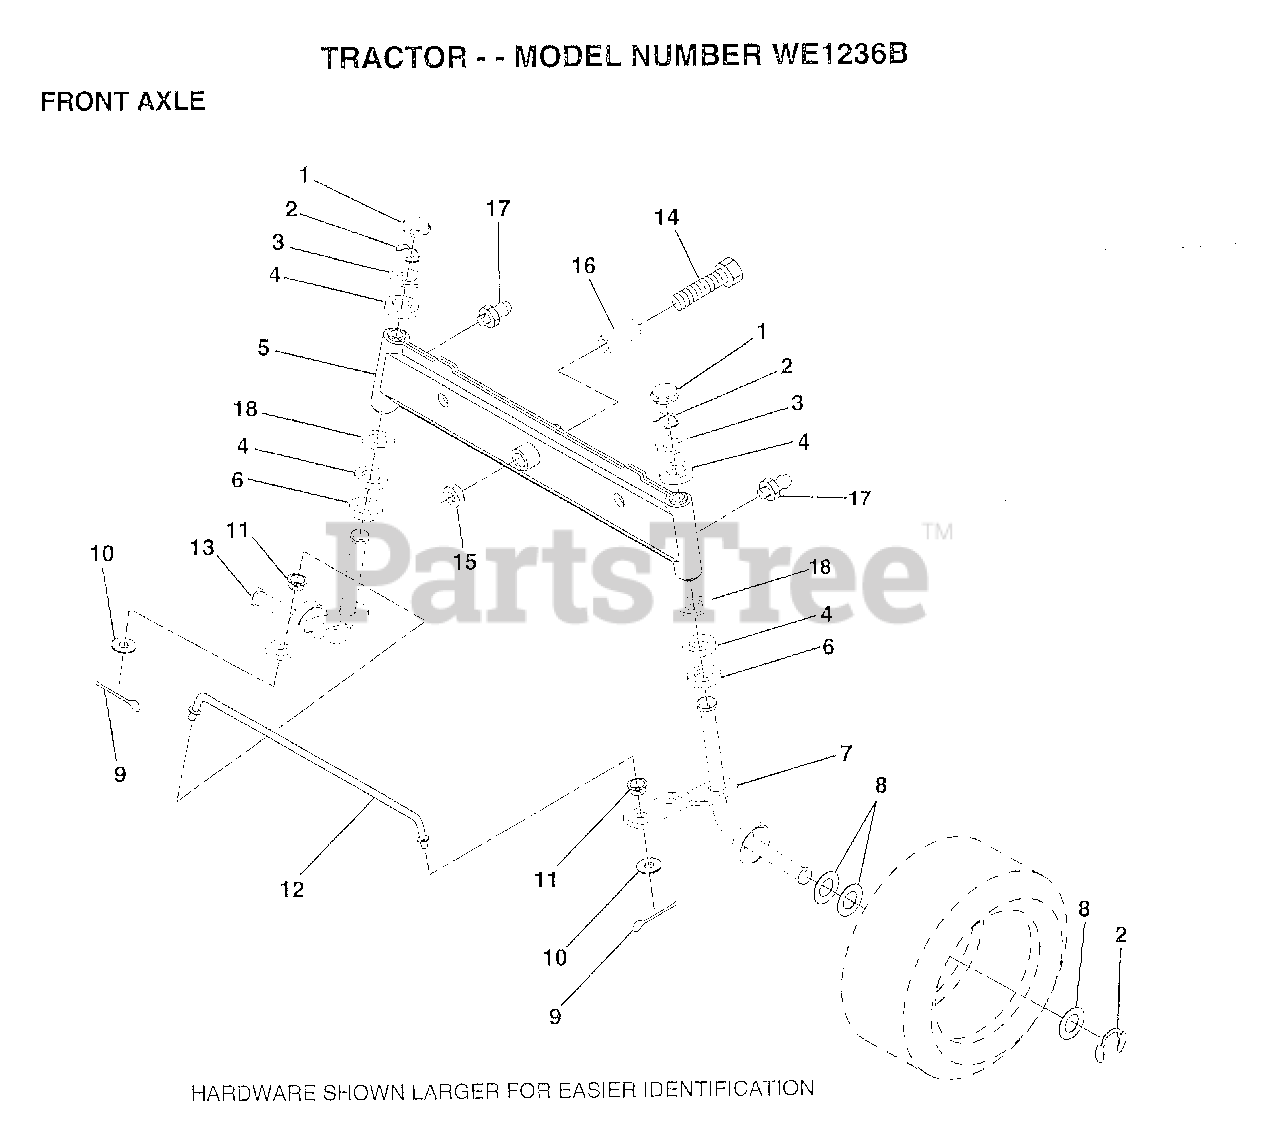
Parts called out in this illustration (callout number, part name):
1	CAP
2	RING
3	WASHER
4	COL. SRTG. BEAR.
5	AXLE ASM FRONT
6	WASHER .T
7	SPINDLE ASM RH
8	WASHER
9	COTTER PIN
10	WASHER
11	BUSHING.DRAGLINK
12	TIE ROD
13	SPINDLE ASM LH
14	BOLT HEX 5/8-11
15	"NUT-LOC,FLANGE LT"
16	BEARING
17	ZERK M
18	WASHER
